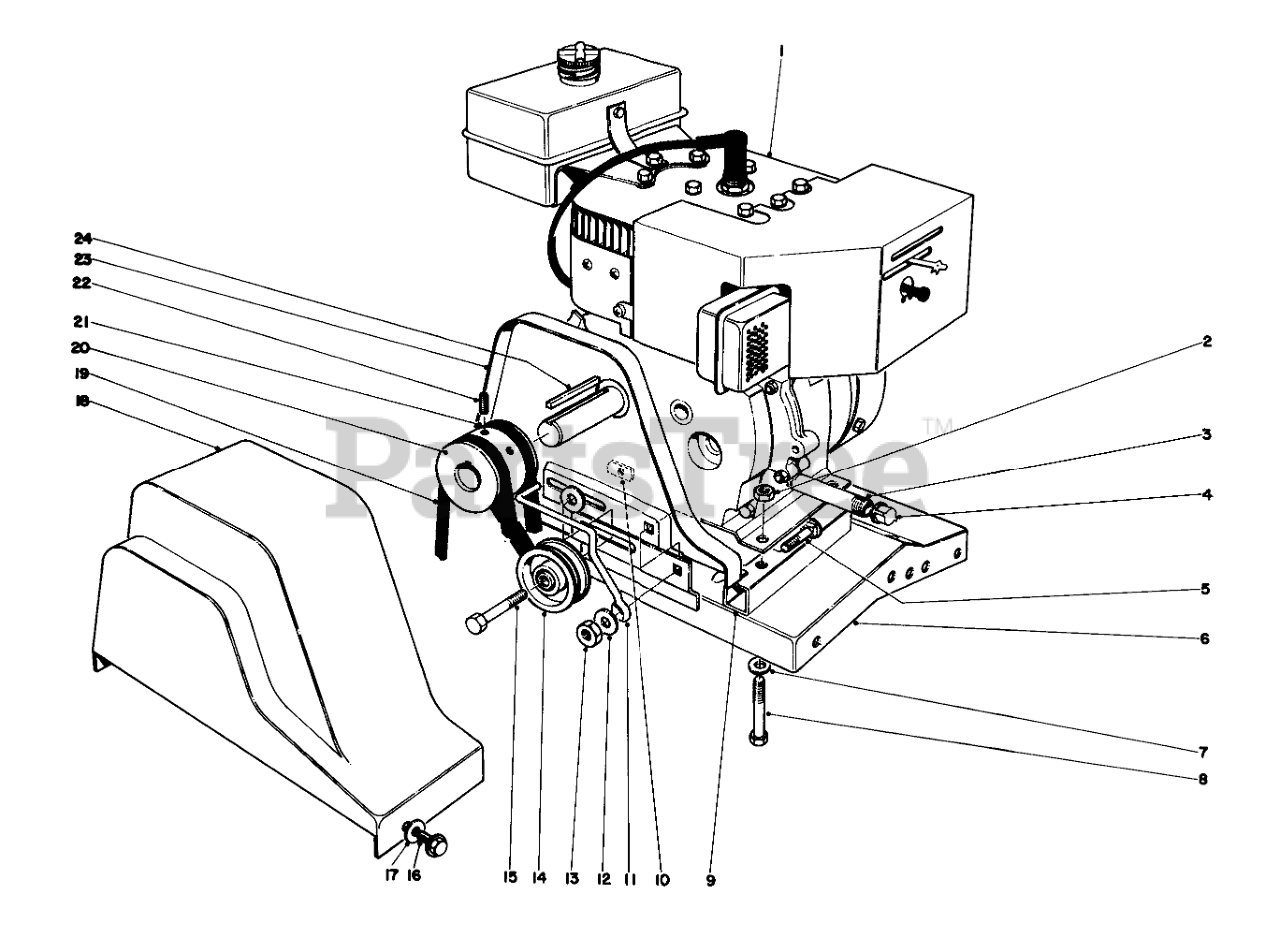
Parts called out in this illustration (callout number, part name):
1	Engine
2	Nut
3	NIPPLE-PIPE
4	CAP-PIPE
5	SCREW-CARR
6	Engine Base
7	WASHER-FLAT
8	SCREW-HH
9	Tube-Engine Mount
10	Weldnut
11	BELT GUIDE
12	WASHER-FLAT
13	NUT-HEX
14	PULLEY-IDLER
15	SCREW-HH
16	Screw, Self-tapping
17	WASHER-FLAT
18	Belt Guard
19	V-Belt
20	Pulley
21	V-Belt
22	Screw-Set
23	Belt Guard
